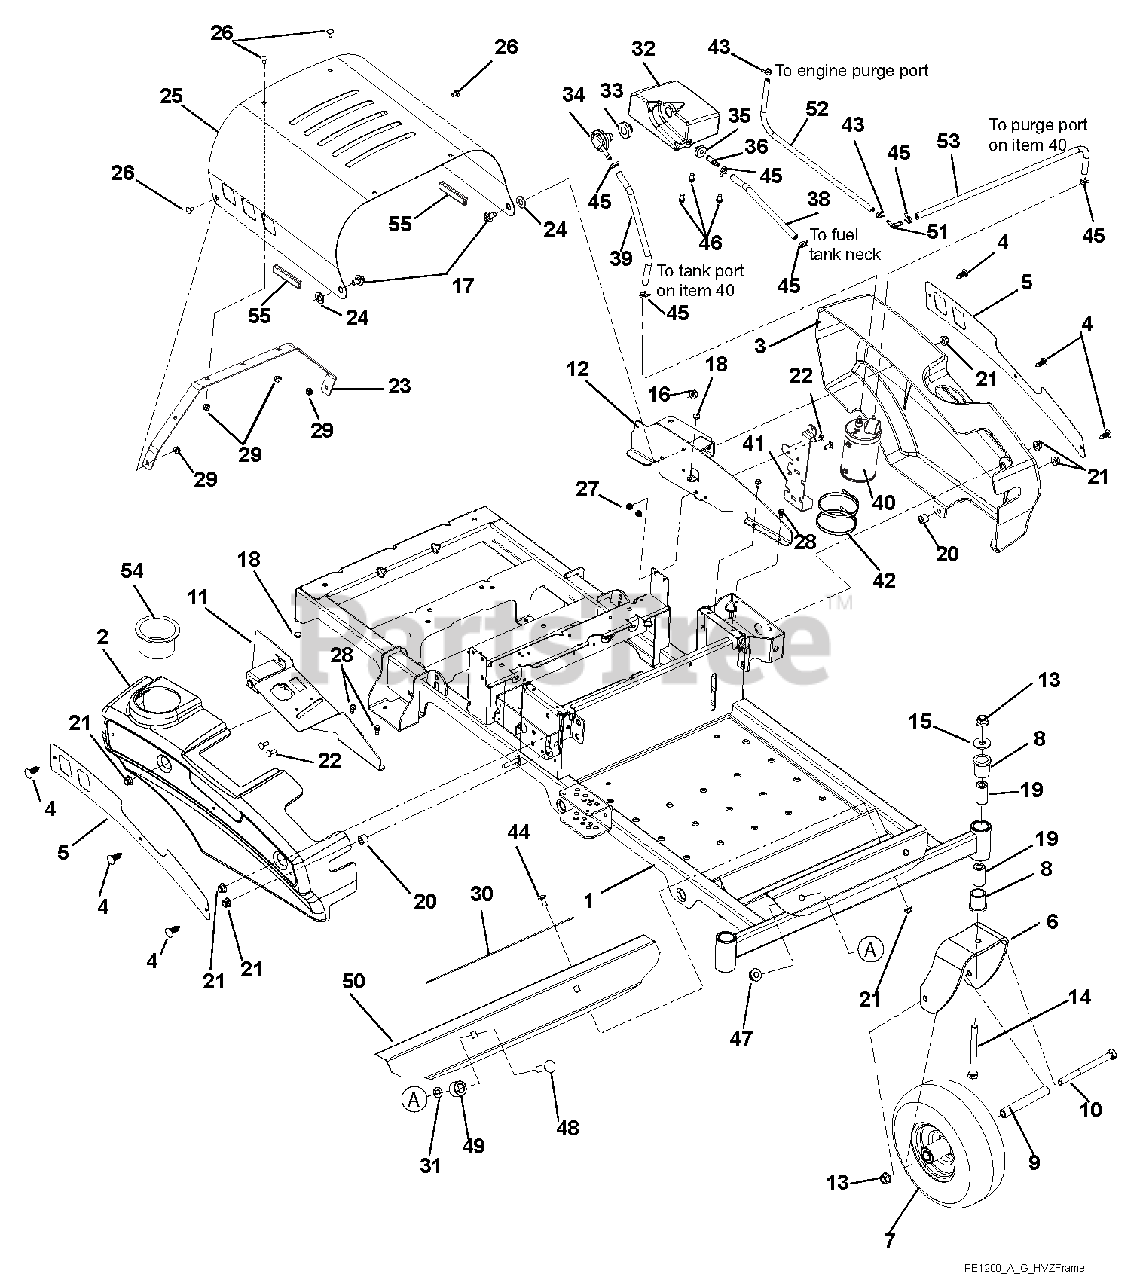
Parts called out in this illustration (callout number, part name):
1	WMT, BBZ FRAME
2	FENDER, RH
3	FENDER, LH
4	RIVET, .25 NYLON PANEL
5	PLATE, FENDER
6	WMT, CASTER FORK
7	TIRE/WHL ASM, FRONT
8	BSHG-FLG 1.00X1.25X1.50X1.50
9	SPACER, ROLLED WHEEL
10	@BLT-HEX .50-13X6.50 GR5 YWZC
11	WMT-RH FENDER MOUNT
12	WLDMNT, LH FENDER MOUNT
13	@NUT-LK-TOP-FLG .50-13 YWZC
14	@BLT-HEX .50-13X5.00 GR5 YWZC
15	WSHR-FL-STL.511X1.441X.125 YWZ
16	@NUT-LK-TOP-FLG .38-16 YWZC
17	BOLT-SHLDR .375-16X.150
18	BUMPER GROMMET
19	SPACER, CASTER .50X1.00X1.84
20	BSHG-SLV .391X.688X.52 PM
21	@NUT-LK-NYL-FLG .31-18 YWZC
22	@BLT-RDHDSQNK .25-20X.75 G5YZ
23	BRACE, HOOD
24	WSHR-FL-NYL .518X1.000X.080
25	HOOD, ZOOM/ZT
26	@BLT-RDHDSQNK .25-20X.50 G5YZ
27	@NUT-LK-NYL-FLG .25-20 YWZC
28	@SCR-TAP .25-20X.50 HWH TR YWZ
29	@NUT-LK-TOP-FLG .25-20 YWZC
30	GRIP, ADHESIVE (1" X 16" BLK)
31	NUT-PUSH, .50
32	TANK, ZOOM/WAW FUEL EXP.
33	GROMMET, REMOTE VENT NITRILE
34	VENT, ROLL-OVER (.25"ID HOSE)
35	BSHG-FLG .375 X 1.062 X .625 R
36	FITTING, STRAIGHT FUEL
37	CLAMP, FUEL LINE
38	HOSE, .25 LOW-PERM BULK GAS
39	HOSE, .25 LOW-PERM BULK GAS
40	CARBON CANISTER, 300CC
41	BRKT-MOUNT, CANISTER BBZ
42	P-PLASTIC TIE STRAP LARGE
43	CLAMP-HOSE, SPRING .188
44	@BLT-RDHDSQNK .31-18X.75 G5YZ
45	CLAMP, FUEL LINE
46	BLT-SERHFWH .312-18X.50 YWZC
47	@NUT-LK-NYL-FLG .50-13 YWZC
48	@BLT-RDHDSQNK .50-13X1.75 G5YZ
49	TUBE, UPPER CONTROL PIVOT
50	FOOTREST
51	FITTING-3/16X1/4 90DEGREE VAC
52	HOSE, .188 LOW-PERM BULK GAS
53	HOSE, .25 LOW-PERM BULK GAS
54	CUPHOLDER, SNAP-IN 3.75OD
55	EDGING, CLUTCH PADDLE - 2.00"
